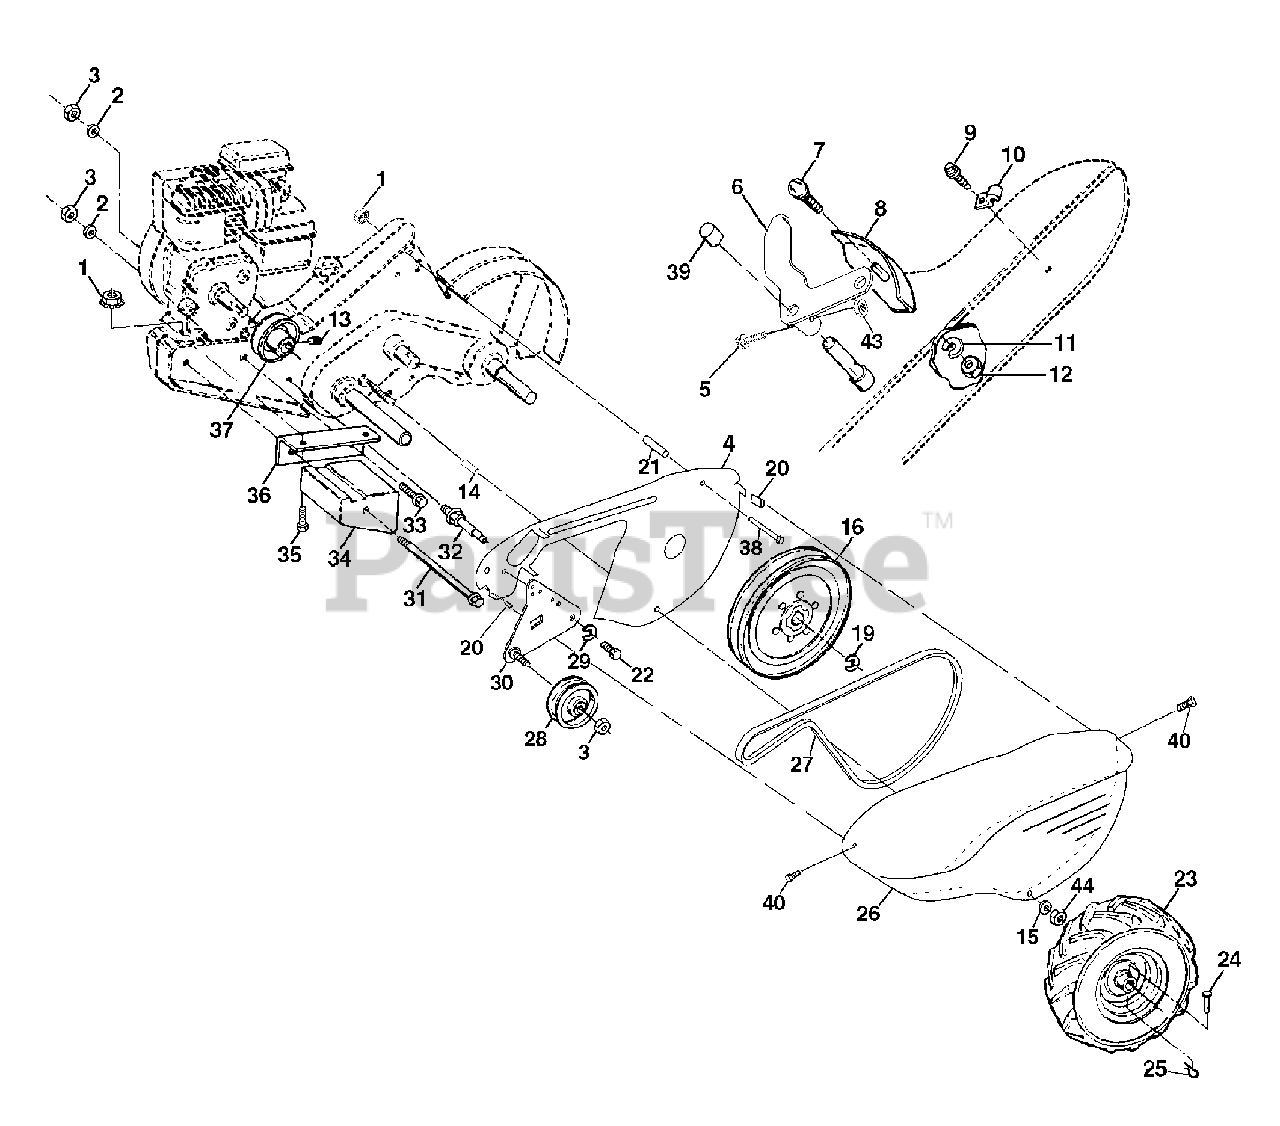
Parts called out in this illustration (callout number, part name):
1	Nut, Keps 5/16-18
2	Washer, Lock 3/8
3	Nut, Hex 3/8-16
4	Shield, Inner Belt Guard RT
5	Screw, Shift Lever
6	Lever, Shift
7	Bolt, Carriage 1/4-20 x 1/2 Gr. 5
8	Plate, Shift Indicator
9	Screw, Hex, Washer Head, Slotted #10-24 x 1/2
11	Washer, Lock 1/4
12	Nut, Hex 1/4-20
13	Screw, Set, Hex 5/16-18 x 3/8
14	Spacer, Split 0.327 x 0.42 x 2.09
15	Washer 11/32 x 11/16 x 16 Ga.
16	Sheave, Transmission
17	Nut, Hex 5/16-18
19	Retainer, Ring
20	Nut J Clip #8
21	Spacer, Split
22	Bolt, Fin Hex 5/16-24 UNF x 1/2
23	Rim
23	Tire Valve
24	Rivet, Drilled
25	Clip, Hairpin
26	Guard, Belt
27	Belt, V
28	Pulley, Idler
29	Ring, Klip
30	Bracket, Idler
31	Bolt, Hex 5/16-16 x 12
32	Shaft, Idler Arm
33	Bolt, Hex 3/8-16 x 1
34	Counterweight, L. H.
35	Bolt, Hex 5/16-18 x 2
36	Bracket, Reinforcement, L. H.
37	Sheave, Engine
38	Bolt, Fin Hex 5/16-18 UNC x 2-3/4
39	Cap, Plunger Blk
40	Screw Hex Wsh Hd #8-18 x 1/2
43	Nut, Lock #10-24
